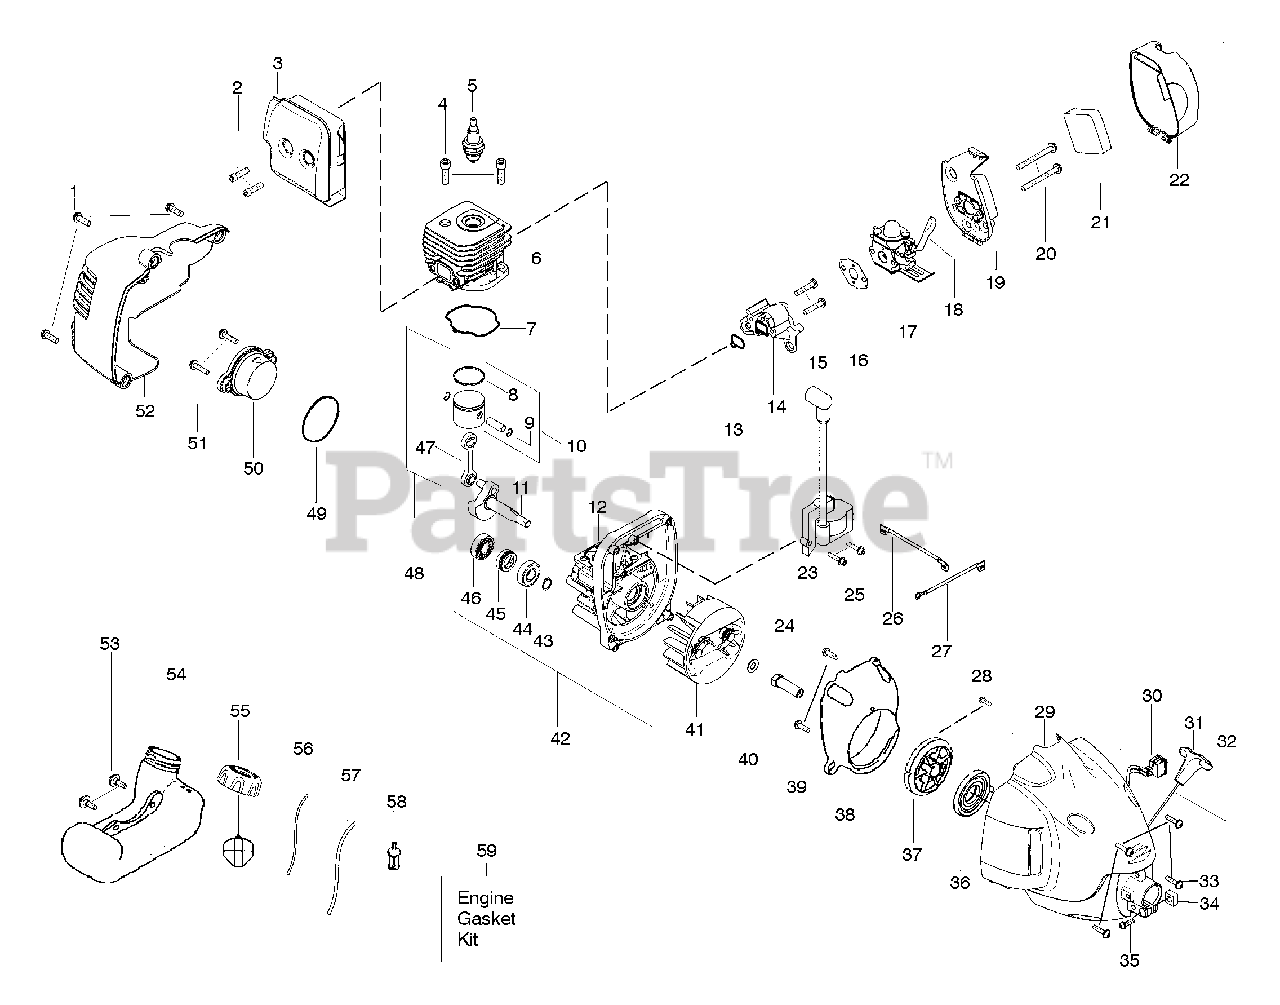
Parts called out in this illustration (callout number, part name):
2	Bolt-Muffler
3	Assy-Muffler/Shield
4	Screw-Cylinder
5	Spark Plug (RCJ 6Y)
6	Cylinder
7	Seal-Cylinder (kit)
8	Piston Ring
9	Retainer-Piston Pin
10	Kit - Piston
11	Assy-Crankshaft
12	Assy-Crankcase
13	Seal-Cyl/Carb. (kit)
14	Adapter-Carb.
16	Gasket-Carb. (kit)
17	Kit-Carb. Zama (C1U-W18)
17	Kit-Carb. Walbro (WT-669)
18	Lever-Choke
21	Foam-Air Filter
22	Cover-Air Box
23	Ignition Module
24	Coupling-Drive
26	Assy-Leadwire
27	Assy-Ground Wire
29	Assy.-Fan Hsg
30	Kit-Switch
31	Handle-Starter
32	Kit - Rope
33	Screw
34	Nut 12-24
35	Screw 12-24
36	Spring-Starter
37	Kit-Starter Pulley
38	Baffle
40	Washer-Flat
41	Assy-Flywheel
42	Assy-C'case & C'shaft
43	Retain. Ring-C'shaft
44	Outer Bearing
45	Seal-C'shaft
46	Inner Bearing
47	Kit-Conn. Rod Assy
48	Kit-Piston / Rod
49	O-Ring-C'case (kit)
50	Assy-Plug
52	Shroud-Rear
53	Retainer-Tank
54	Assy-Fuel Tank
55	Assy-Fuel Cap
56	Kit-Fuel Line (Small)
57	Kit-Fuel Line (Large)
58	Assy-Fuel Pickup
59	Kit-Engine Gasket
